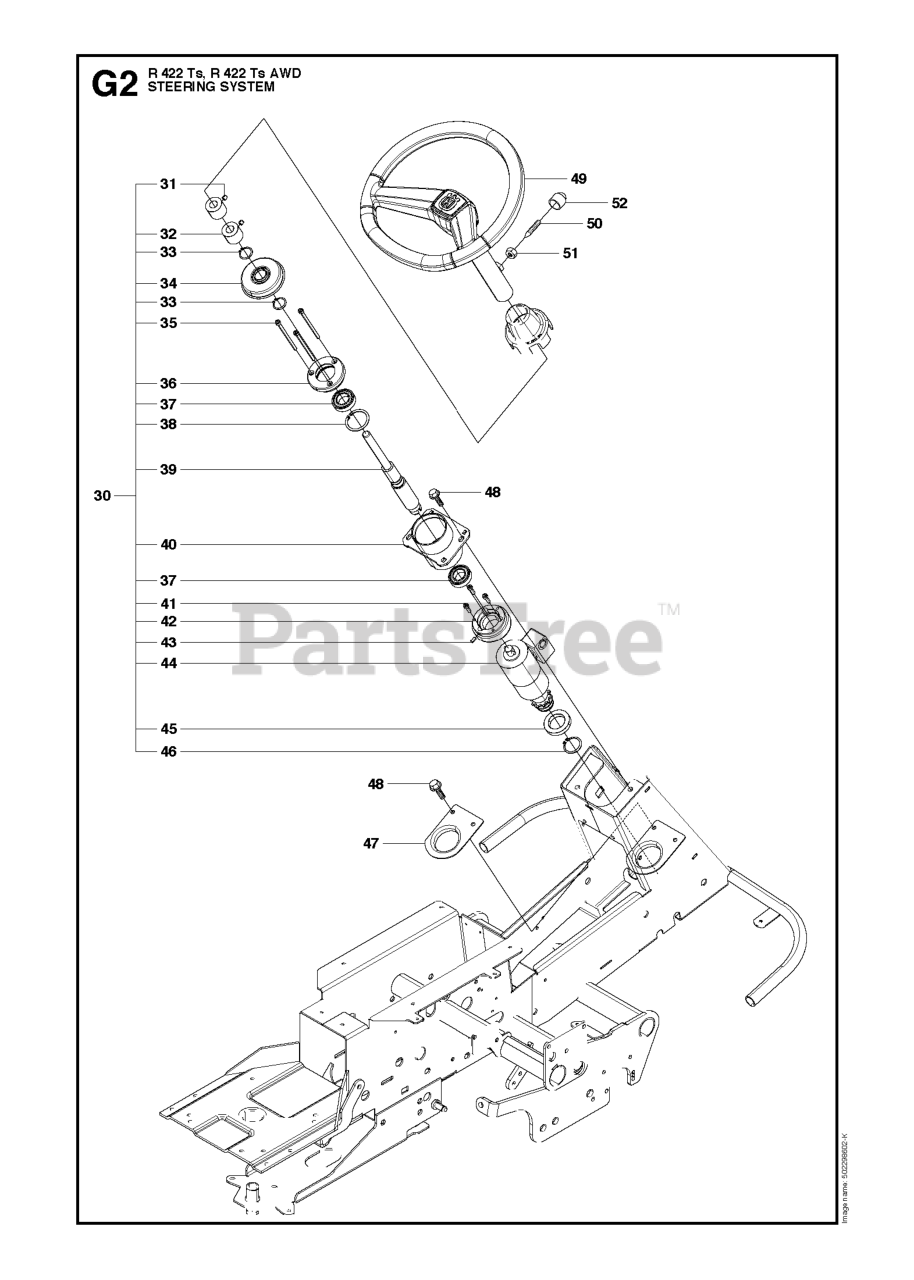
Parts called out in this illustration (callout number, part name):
32	SPACER
33	RETAINING RING SGA 25
35	SCREW IHSCM.
37	Ball Bearing 6005-2rs
38	CIRCLIP SGH 47
41	SCREW MC6S 6X20
43	SPRING PIN
44	COMFORT STEERING
51	NUT
52	PROTECTIVE COVER
